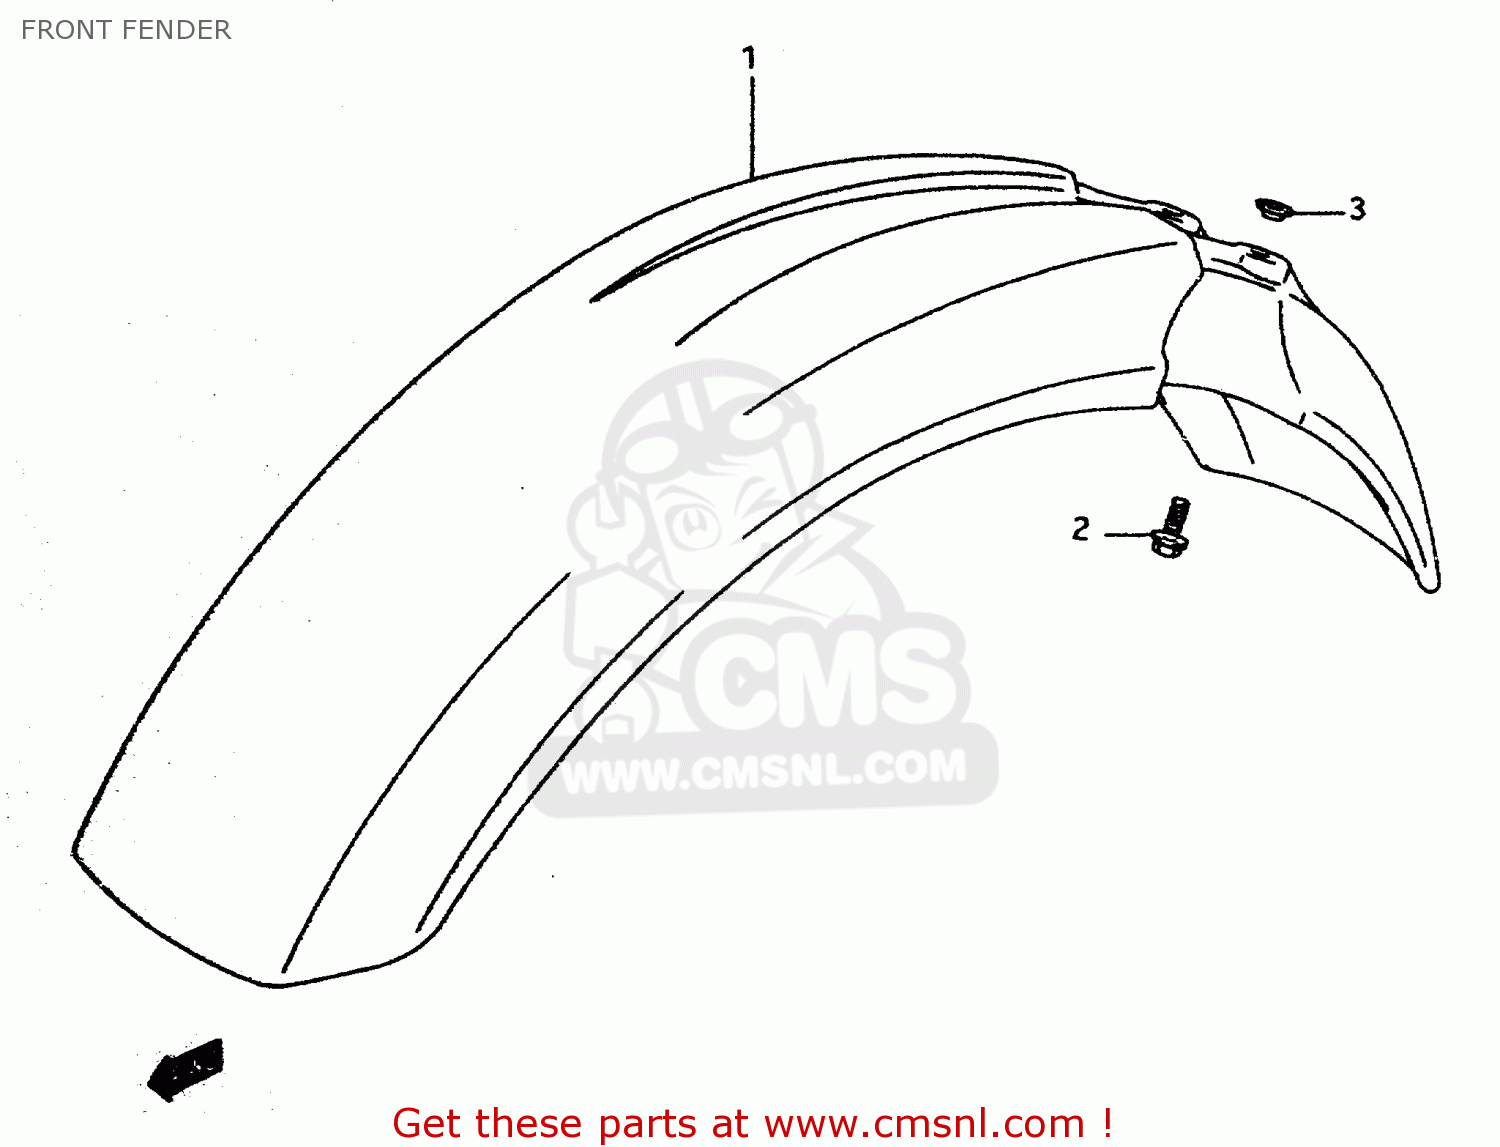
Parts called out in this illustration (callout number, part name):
1	FENDER,FR
2	BOLT(6X16)
3	WASHER
